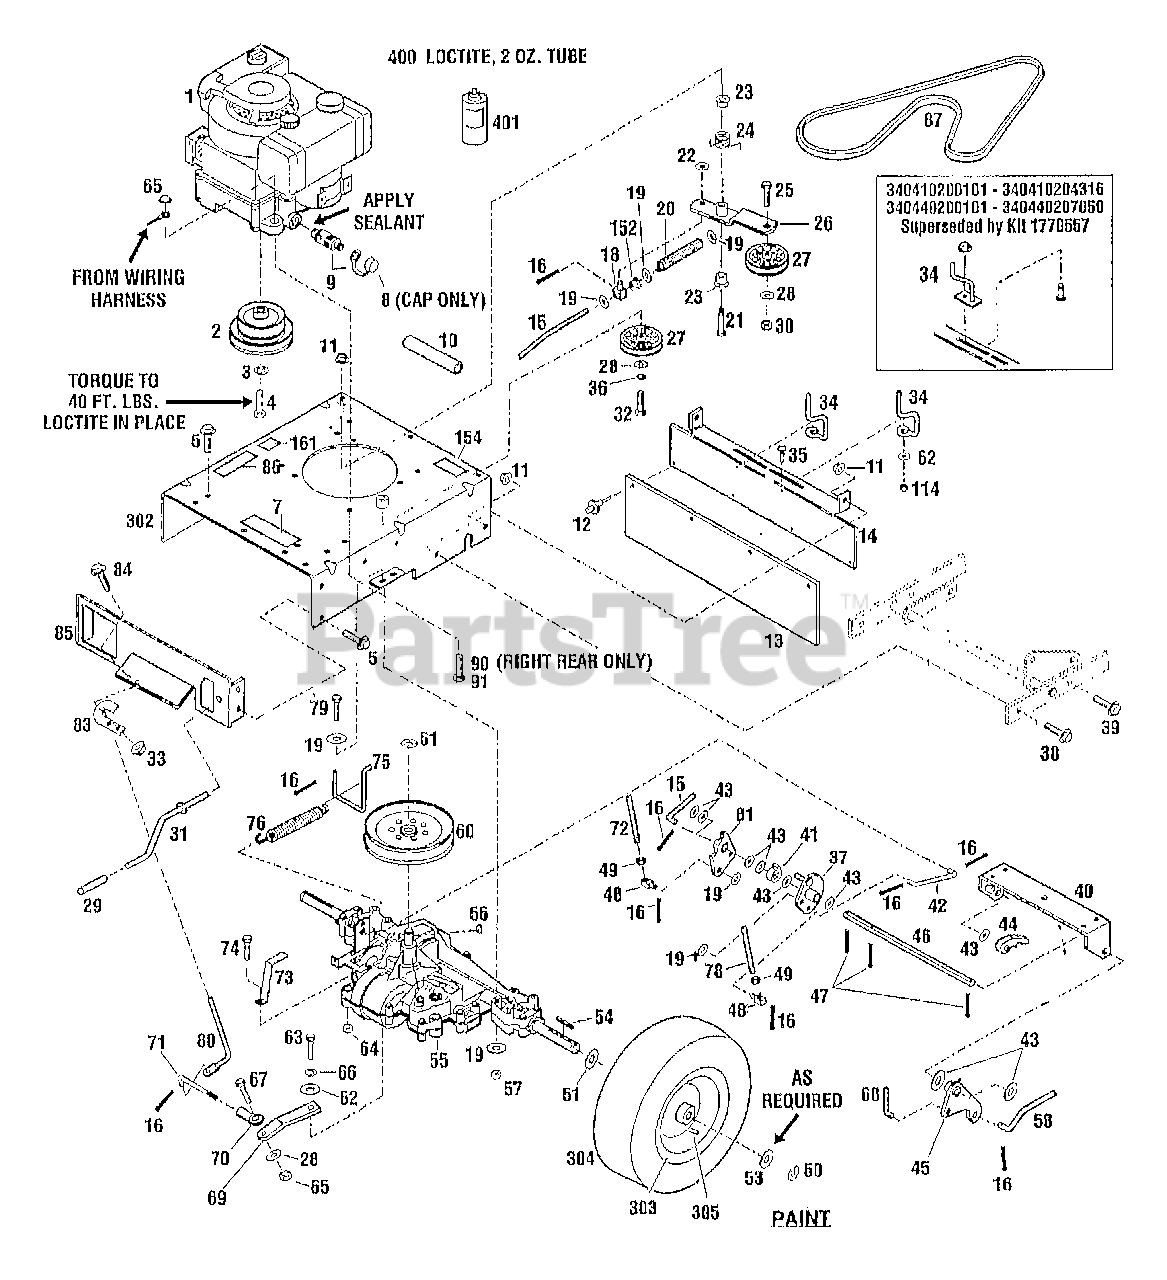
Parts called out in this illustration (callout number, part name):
1	ENGINE, 8.5HP ELEC. START MODEL 196707- 0141 (34041)
1	ENGINE, 8.5HP RECOIL START MODEL 196702- 0142 (34044)
2	ENGINE SHEAVE-HW&WC (SUPERCEDES 1764991)
3	WASHER-LK .438 ZP
4	SCR-HH 7/16-20X1.25 G5ZP
5	SCR-HFLK 5/16-18X.62 G5ZP
7	DECAL-WARNING
8	CAP-OIL DRAIN
9	ASSM-OIL VALVE (INCL. 8)
10	HOSE-OIL DRAIN
11	NUT-HFLK 3/8-16 ZP
12	RIVET-POP 3/16 X 5/8
13	FLAP-DEFLECTOR
14	BRACKET-FLAP MTG
15	ROD-LOWER TRANS
16	PIN-COTTER .093X.625
18	BLOCK-PIVOT
19	WASHER-FLAT 5/16 SAE
20	SPRING-COMPRESSION
21	SCR-SHLDR 3/8-16
22	WASHER-.632X.39X.0329
23	BUSHING-.5X.5 NYLON FLNG
24	SPRING-TORSION
25	SCR-CARR 3/8-16X1.75 G5 ZP
26	ASSM-IDLER ARM ZP
28	WASHER-FLAT 3/8 SAE
29	GRIP-PLASTIC
30	NUT-LOCK 3/8-16
31	ASSM-CRANK LIFT
32	SCR-HH 3/8-16X1.75 G5 ZP
33	NUT-HF/LK 1/4-20 ZP
34	KIT-BELT GUIDE
34	ASSM-BELT GUIDE
35	SCR-CARR 1/4-20X.75 G2 ZP
36	WASHER-LK .375 @ DEPL
37	ASSM-BRAKE ARM PIVOT
38	SCR-HFLK 3/8-16X1.25 ZP
39	SCR-HFLK 3/8-16X1.00 ZP
40	ASSM-PIVOT BRACKET
41	CAM-INTERLOCK
42	ROD-LOWER BRAKE
43	WASHER-FLAT 1.0X.516X.031
44	LATCH-INTERLOCK
45	ASSM-BLADE PIVOT ARM
46	SHAFT-PIVOT
47	PIN-COTTER .125 X .75 ZP
48	BLOCK-SWIVEL ZP
49	NUT-HEX JAM 5/16-18
50	RING-RET."E".577 ID
51	WASHER-1.5X.755X.062
53	WASHER-1.25X.765X.049
54	KEY-.188 SQ X 2.5
55	PEERLESS TRANSMISSION ASSEMBLY, MODEL 915- 021 (SEE GRIDS D-9/10 FOR BREAKDOWN)
57	NUT-TOP/LK 5/16-18 ZP
58	ROD-LOWER BLADE
60	SHEAVE-TRANS DRIVE
61	RING-RETAIN .625 ID
62	WASHER-FLAT 1/4 SAE
63	SCR-HH 1/4-28X.75 G5 ZP
64	NUT-HFLK 5/16-18 ZP
65	NUT-H/LK 3/8-16
66	WASHER-LK .25 ZP
67	SCR-HH 3/8-16X1.25
68	ROD-UPPER BLADE
69	ARM-TRANSMISSION ZP
70	JOINT-BALL
71	ROD-SHIFT LINK
72	ROD-UPPER TRANS MOWER
73	BRKT-BELT SUPPORT
74	SCR-HH 5/16-18X2.00
75	ROD-SPRING ATTACHMENT
76	SPRING-EXTENSION
78	ROD-UPPER BRAKE
79	SCR-HH 5/16-18X2.75 G5 ZP
80	ASSM-SHIFT LEVER
81	ASSM-CLUTCH ARM PIVOT
83	BRKT-SHIFT ROD MTG
84	SCR-HFLK 1/4-20X.50 ZP
85	PLATE-BACK
86	DECAL-WARNING THROWN OBJECT
87	BELT-TRANS DRIVE
90	SCR-THRD FRM 3/8-16X1.50
91	SCR-HH 3/8-16X1.0 THDFM
114	NUT-HT LK 1/4-20
154	DECAL-AMERICAN LEGEND-SM
161	DECAL-STEP
302	ASSM-FRAME (INCL. 7 & 86)
304	TIRE
305	STEM-VALVE
400	LOCTITE-242 (.5 ML TUBE)
401	PAINT-RED SPRAYCAN POWDER
